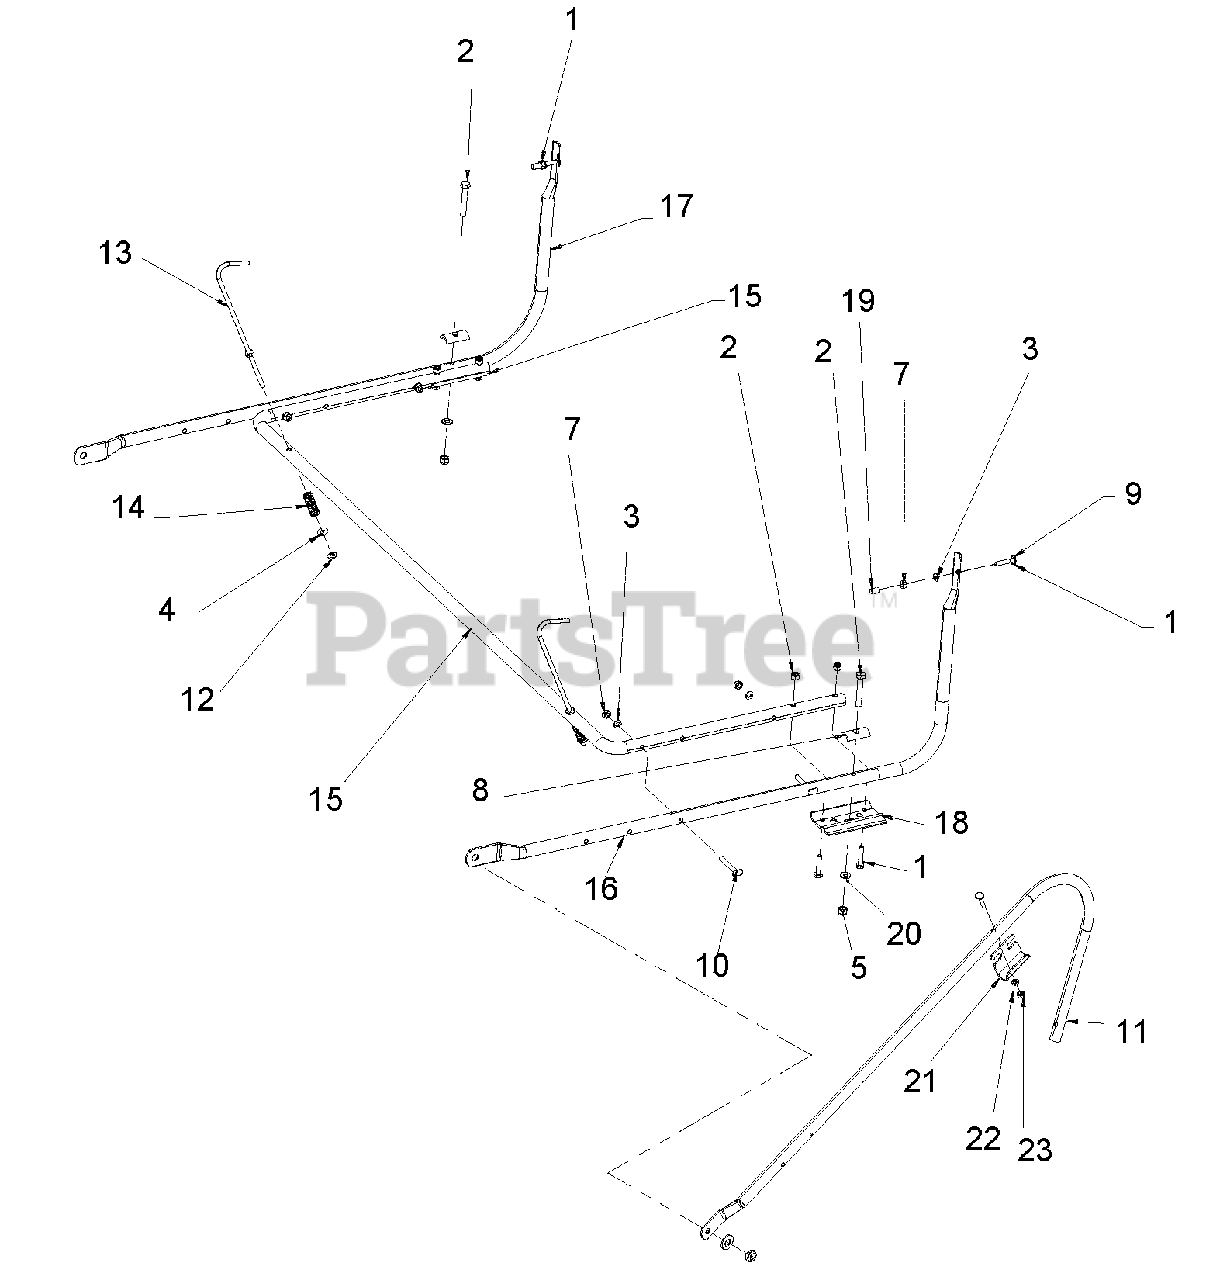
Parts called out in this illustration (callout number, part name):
1	Bolt .25 -20 x 1.25 Hex 5
2	Bolt .31-18 x 2.00 Hex 5
3	Washer .250 Lock
4	Washer, .250 x .625 x .065 Flat
5	Nut 5/16-19 Nyloc
6	Nut 1/4-20 Nyloc
7	Nut, 1/4-20 Hex 5
9	Bolt, 1/4-20 x 1.25 Contour Head
10	Bolt, 1/4-20 x 2.00 Contour Head
11	Frame, Upper Left Hand TE
12	Nut, 1/4 Speed
13	Basket Stop
15	Frame Support, 74-3/8"
16	Lower Support Frame, Right
17	Lower Support Frame, Left
18	Plate Caster
19	Tube Cap, 1/4
20	Washer .313 x .688 x .065
21	Bracket, Pivot
22	Washer, .250 Med. Spring Lock
23	Nut, 1/4-20 Standard Hex 5
